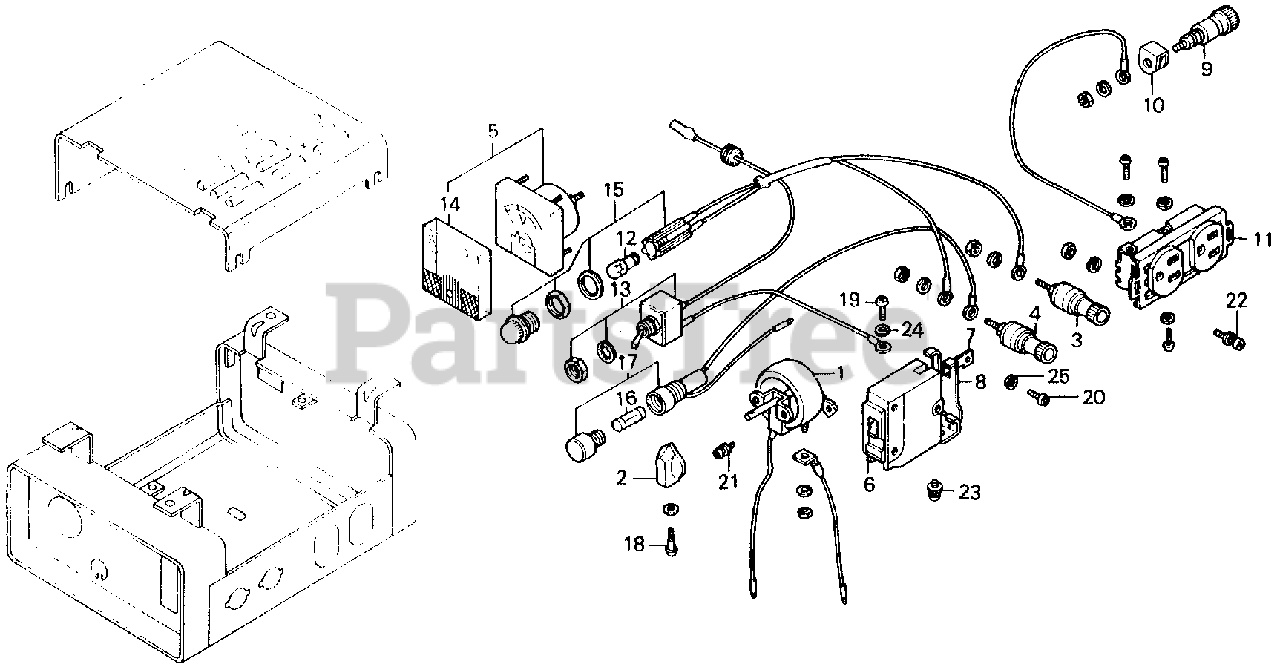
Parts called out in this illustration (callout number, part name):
1	RESISTOR, VARIABLE (NOT AVAILABLE)
2	KNOB, ADJUSTING
3	TERMINAL, D.C. OUT (+)
4	TERMINAL ASSY. B
4	TERMINAL, D.C. OUT (-)
5	VOLTMETER ASSY. (150V SCALE)
6	BREAKER, CIRCUIT
6	BREAKER, CIRCUIT (10A)
7	TERMINAL, BREAKER
8	SUPPORT, BREAKER (NOT AVAILABLE)
9	TERMINAL ASSY., GROUND
9	TERMINAL ASSY., GROUND (NOT AVAILABLE)
10	PLATE, GROUND
11	RECEPTACLE (15A 125V)
11	RECEPTACLE (15A-125V)
12	BULB (24V2W)
13	SWITCH ASSY., ENGINE (NOT AVAILABLE)
14	LENS, METER
15	SOCKET ASSY., PILOT LAMP (NOT AVAILABLE)
16	FUSE (15A)
17	HOLDER ASSY., FUSE
18	BOLT, KNOB (NOT AVAILABLE)
19	SCREW, PAN (4X8)
20	SCREW, PAN (5X10)
21	SCREW-WASHER (3X6)
22	SCREW-WASHER (4X12)
23	SCREW-WASHER (5X8)
24	WASHER, SPRING (4MM)
25	WASHER, SPRING (5MM)
